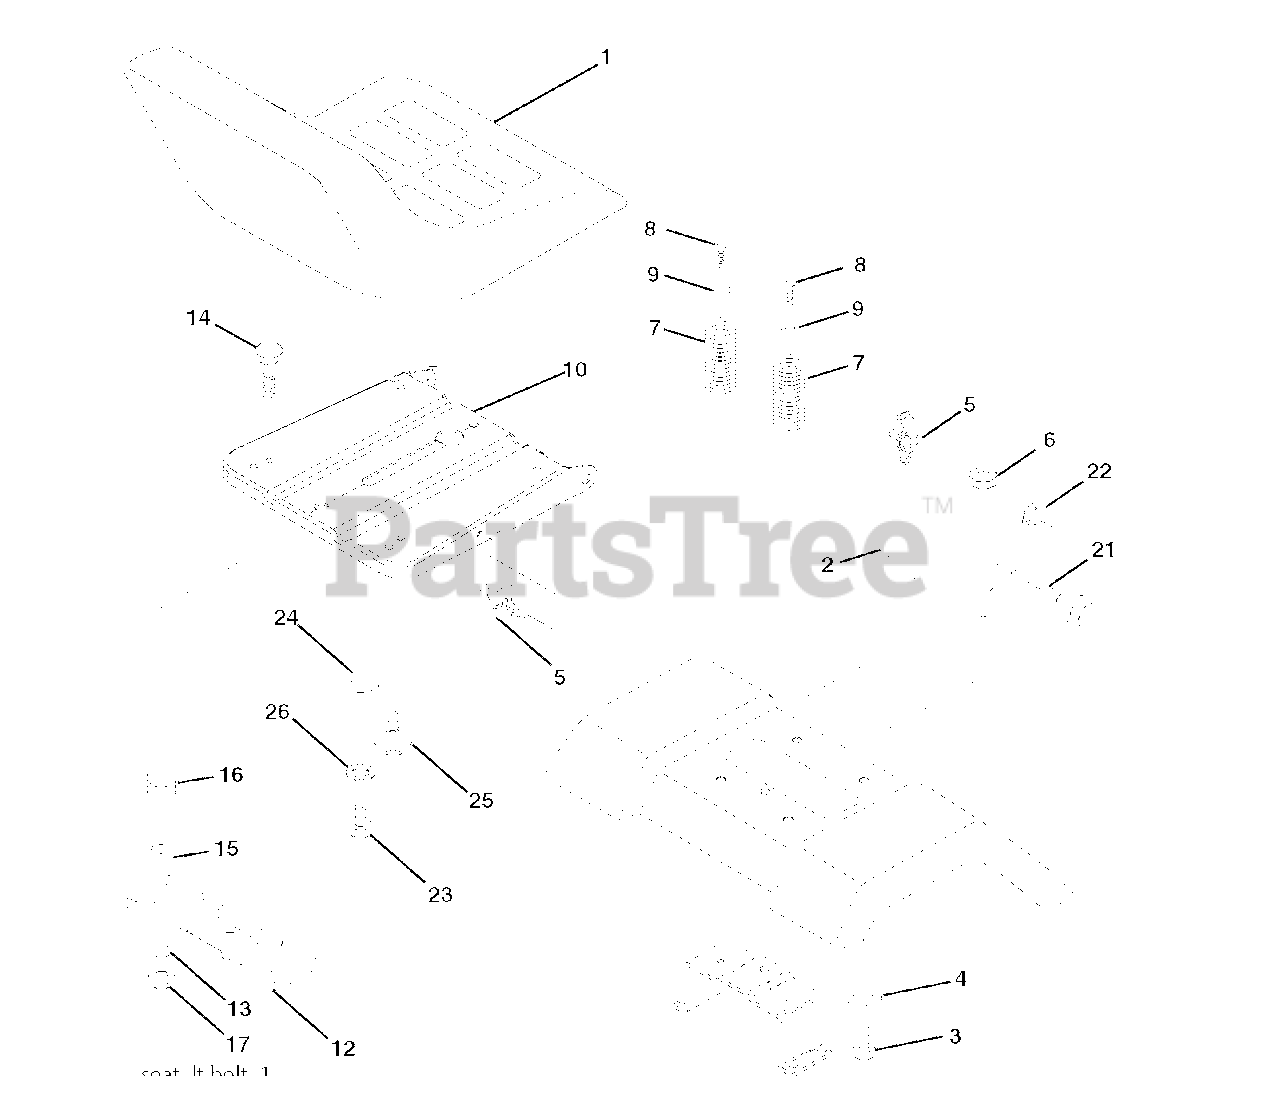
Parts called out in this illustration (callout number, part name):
1	SEAT.XG090.BLK.KB/BLT.NO-LOG
2	SEAT PIVOT BRKT
4	WASHER PM
5	PUSH CLIP
6	NUT
7	SPRING COMPRESSION
8	SCREW 3/8-16X1
9	WASHER
10	PAN.ASM.SEAT.1SLOT
12	BRKT.MNTNG.SWITCH.SEAT
